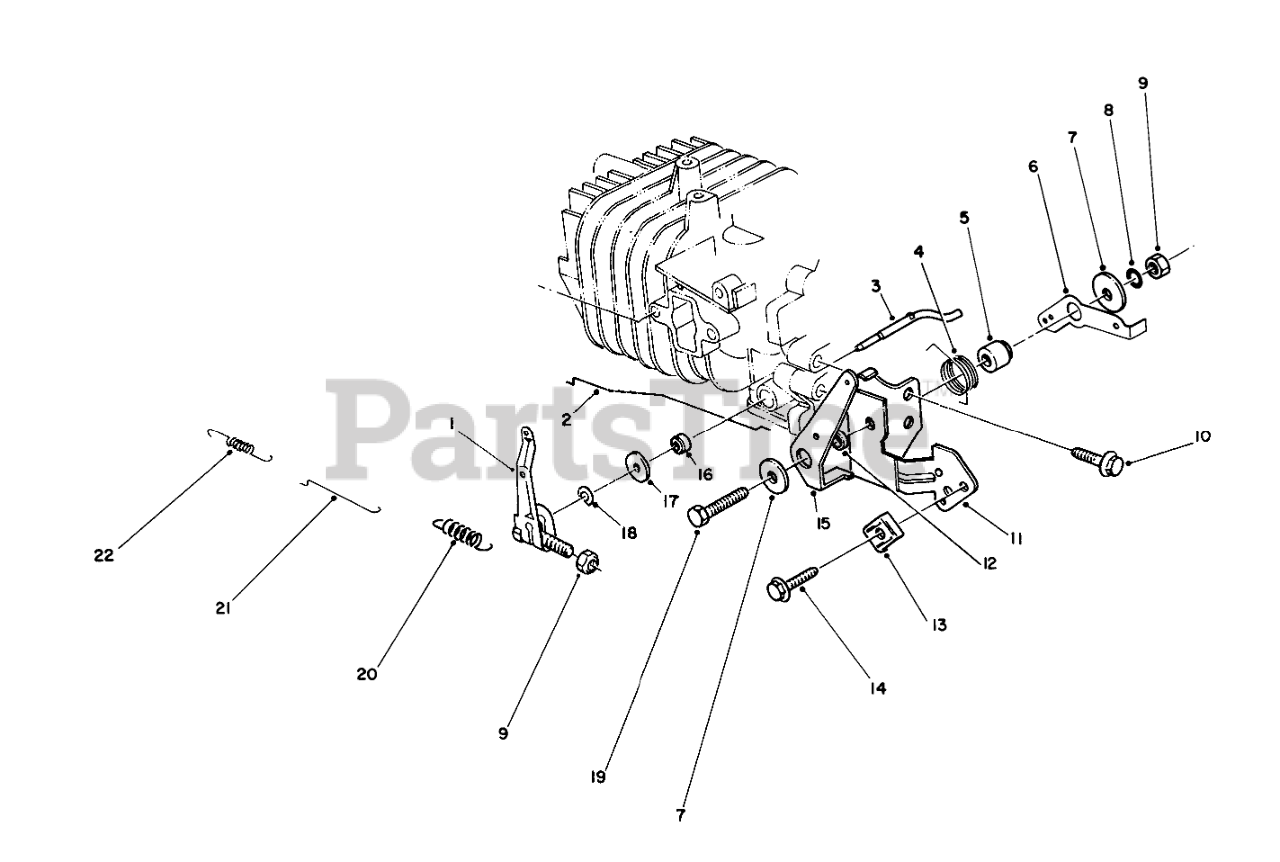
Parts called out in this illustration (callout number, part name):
1	ARM-GOVERNOR
2	ROD-CHOKE
3	Shaft-Govemor
4	SPRING-CHOKE LEVER
5	Gov Lever Spacer
6	LEVER-SPRING, GOVERNOR
7	WASHER
8	LOCKWASHER
11	BRACKET-THROTTLE, CONTROL
12	SPACER-CHOKE LEVER
13	CLAMP
15	LEVER-CONTROL, CHOKE
16	SEAL-OIL
17	WASHER
18	E-RING
20	SPRING-GOVERNOR
21	ROD-CARBURETOR
22	SPRING
